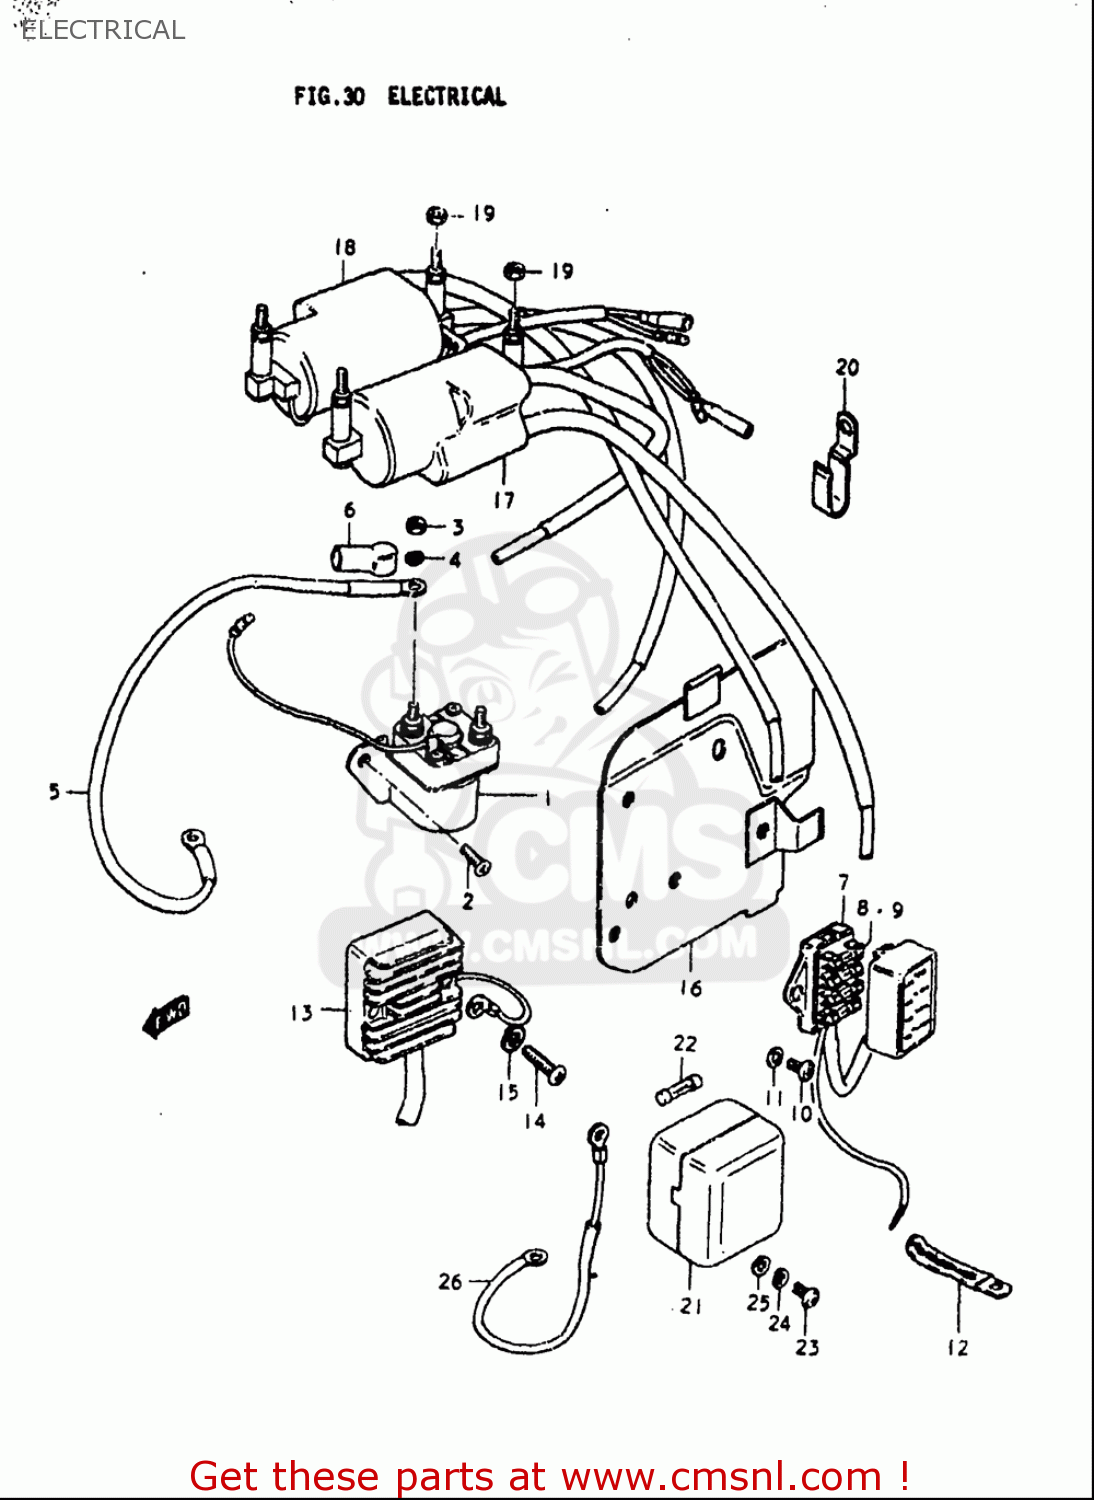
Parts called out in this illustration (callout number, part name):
1	RELAY ASSY,STARTING MOTOR
2	SCREW
3	NUT
4	WASHER,LOCK
6	CAP,STARTER MOTOR LEAD
7	BOX ASSY,FUSE
8	FUSE(10A)
9	FUSE(15A)
10	SCREW
11	WASHER
12	CLAMP(L:65)
13	RECTIFIER ASSY
14	SCREW
15	WASHER,LOCK
17	COIL ASSY,IGNITION
18	COIL ASSY,IGNITION
19	NUT
20	CLAMP
22	FUSE(10A)
23	SCREW
24	WASHER,LOCK
25	WASHER
